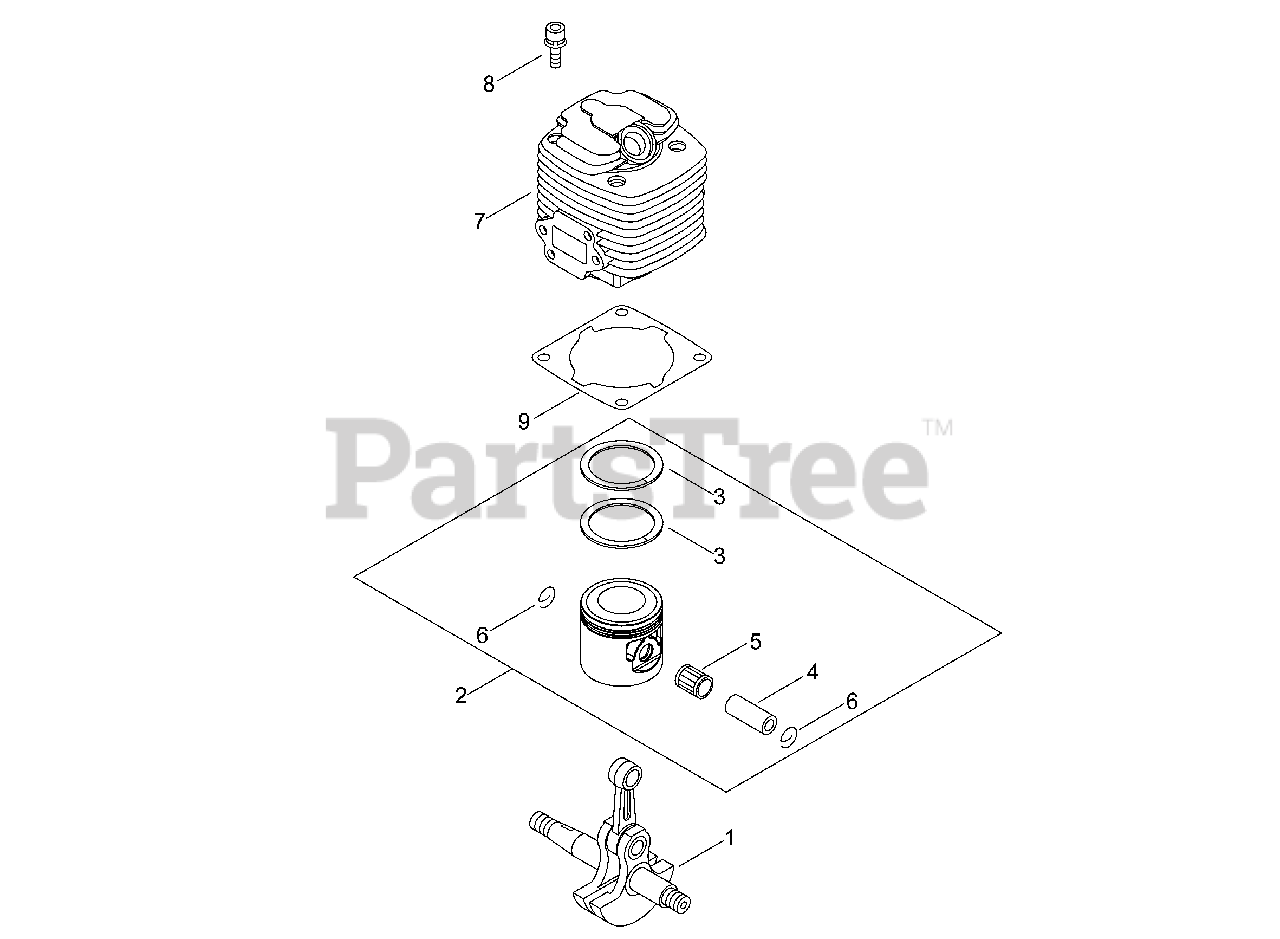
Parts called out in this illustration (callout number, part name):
1	CRANKSHAFT ASSY
2	PISTON KIT
3	RING, PISTON
4	PIN, PISTON
5	BEARING, NEEDLE
6	RING, SNAP Ø10
7	CYLINDER
8	BOLT 5×22
9	GASKET, CYLINDER
